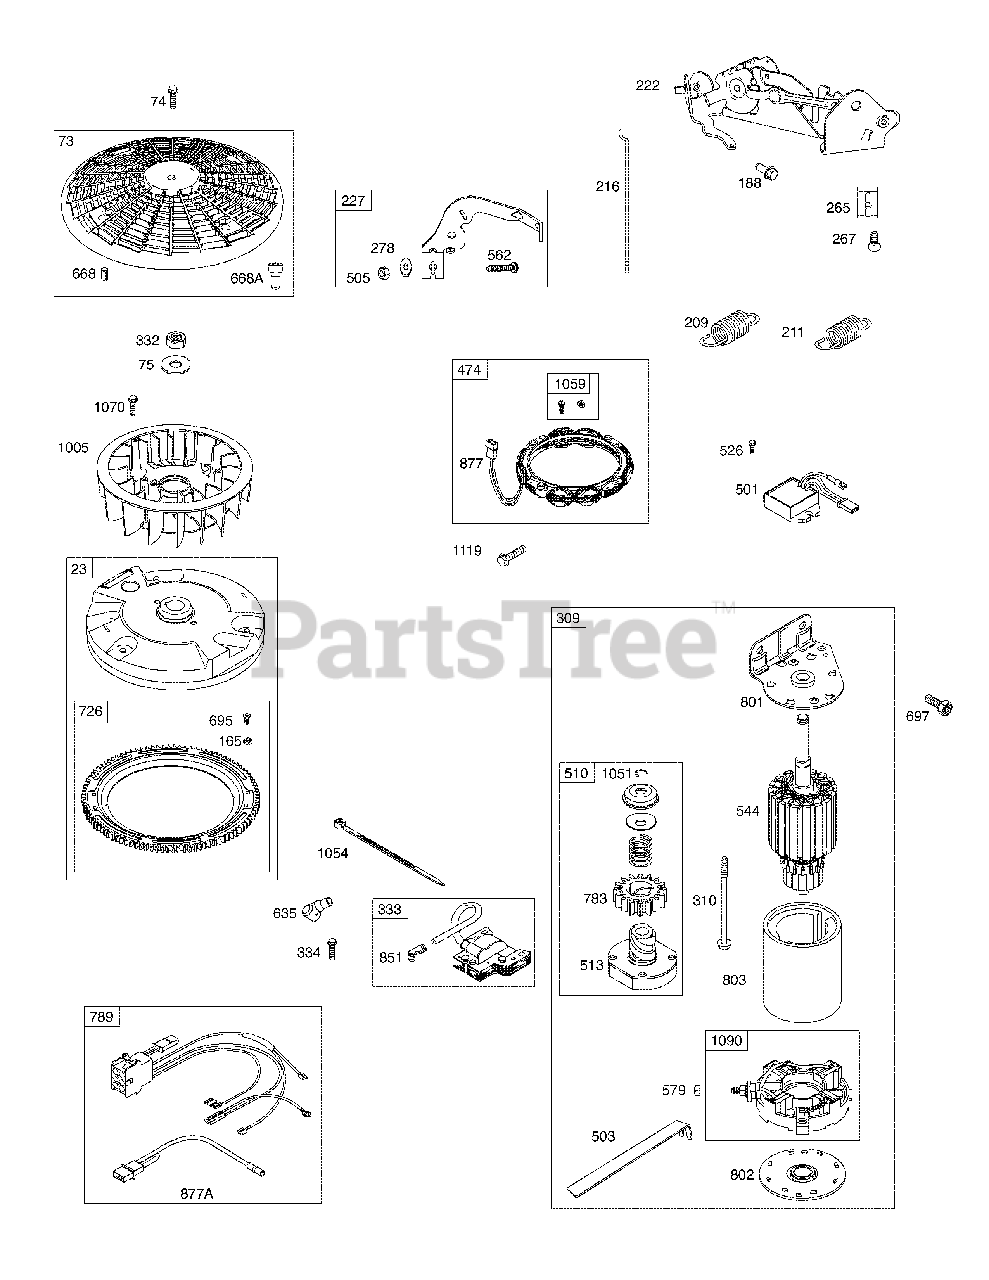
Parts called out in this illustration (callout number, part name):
1	Cylinder Assembly
2	Kit-Bushing/Seal (Magneto Side)
3	Oil Seal (Magneto Side)
4	EngineSump
5	Cylinder Head (Cylinder #1)
5A	Cylinder Head (Cylinder #2)
7	Cylinder Head Gasket
8	Breather Assembly
9	Breather Gasket
10	Screw (Breather Assembly)
11	Breather Tube
12	Crankcase Gasket
13	Screw (Cylinder Head)
15	Oil Drain Plug
16	Crankshaft
20	Oil Seal (PTO Side)
22	Screw (Crankcase Cover/Sump)
23	Flywheel
24	Flywheel Key
25	Piston Assembly (Standard)
25	Piston Assembly (.020" Oversize)
26	Ring Set (Standard)
26	Ring Set (.020" Oversize)
27	Piston Pin Lock
28	Piston Pin
29	Connecting Rod
32	Screw (Connecting Rod)
33	Exhaust Valve
34	Intake Valve
35	Valve Spring (Intake)
36	Valve Spring (Exhaust)
40	Valve Retainer
42	Valve Keeper
45	Valve Tappet
48	Short Block
50	Intake Manifold
51	Intake Gasket
51A	Intake Gasket
53	Stud (Carburetor)
54	Screw (Intake Manifold)
73	Rotating Screen
74	Screw (Rotating Screen)
75	Washer (Flywheel)
95	Screw (Throttle Valve)
98	Idle Speed Kit
104	Float Hinge Pin
105	Float Needle Valve
108	Choke Valve
117	Main Jet (Standard) (Left Jet)
117A	Main Jet (Standard) (Right Jet)
118	Main Jet (High Altitude) (Left Jet)
118A	Main Jet (High Altitude) (Right Jet)
121	Carburetor Overhaul Kit
125	Carburetor
130	Throttle Valve
131	Throttle Shaft Kit
133	Carburetor Float
135	Fuel Transfer Tube
137	Float Bowl Gasket
141	Choke Shaft Kit
142	Carburetor Nozzle
146	Timing Key
150	Nozzle Gasket
163	Air Cleaner Gasket
165	Nut (Ring Gear)
177	O-Ring Seal (Dipstick)
187	Fuel Line (Cut to Required Length)
188	Screw (Control Bracket)
192	Rocker Arm Adjuster
197	Screw (Back Plate)
209	Governor Spring (Yellow/Black)
211	Governed Idle Spring (Orange)
212	Throttle Link
216	Choke Link
217	Choke Return Spring
219	Governor Gear
220	Washer (Governor Gear)
221	Governor Cup
222	Control Bracket
227	Governor Control Lever
231	Screw (Choke Valve)
239	Oil Pressure Switch
240	Fuel Filter
250	Breather Retainer
252	Oil Collector
265	Casing Clamp
267	Screw (Casing Clamp)
276	Sealing Washer (Fuel Solenoid)
278	Washer (Governor Control Lever)
287	Screw (Dipstick Tube)
304	Blower Housing
305	Screw (Blower Housing)
305A	Screw (Blower Housing to Intake Elbow)
306	Cylinder Shield (Cylinder #2)
307	Screw (Cylinder Shield) (1.4-20 x 2.3)
309	Starter Motor
310	Screw (Starter Motor)
332	Nut (Flywheel)
333	Magneto Armature
334	Screw (Magneto Armature)
337	Spark Plug
358	Engine Gasket Set
385	Screw (Fuel Pump)
387	Fuel Pump
404	Washer (Governor Crank)
415	Plug (Oil Pressure Switch)
418	Carburetor Plate
431	Intake Elbow
445	Air Cleaner Cartridge Filter
447	Screw (Air Guide Cover) 10-24 x 7.16)
447A	Screw (Air Guide Cover)
467	Air Cleaner Knob
474	Alternator
501	Regulator
503	Starter Strap
505	Nut (Governor Control Lever)
510	Starter Drive
513	Drive Clutch
523	Dipstick
524	Dipstick Tube Seal
525	Dipstick Tube
526	Screw (Regulator)
544	Starter Armature
552	Governor Crank Bushing
552A	Governor Crank Bushing
562	Screw (Governor Control Lever)
573	Back Plate
579	Nut (Starter Cable)
601	Hose Clamp (Black)
601A	Hose Clamp (Green)
615	Governor Shaft Retainer
616	Governor Crank
617	O-Ring Seal (Intake Manifold) (Red)
628	Screw (Fuel Pump Bracket)
633	Choke Seal/Throttle Shaft
635	Spark Plug Boot
654	Nut (Carburetor)
668	Spacer (Rotating Screen)
668A	Spacer (Rotating Screen)
672	Carburetor Plate Gasket
691	Governor Shaft Seal
695	Screw (Ring Gear)
697	Screw (Drive Cap)
718	Locating Pin
741	Timing Gear
742	E-Ring Retainer (Governor Crank)
750	Screw (Oil Pump Cover)
783	Pinion Gear
788	Fuel Pump Bracket
789	Wiring Harness
798	Screw (Rocker Arm)
803	Starter Housing
847	Dipstick/Tube Assembly
851	Spark Plug Terminal
865	Air Guide Cover (Cylinder #1)
865A	Air Guide Cover (Valley)
868	Valve Seat
877	Alternator Wire/Connector
877A	Alternator Wire/Connector
883	Exhaust Gasket
914	Screw (Rocker Cover)
918	Vacuum Hose
943	O-Ring Seal (Oil Pump Cover)
947	Fuel Solenoid
965	Oil Pump Cover
967	Pre-Cleaner Filter
968	Air Cleaner Cover
975	Float Bowl
987	Throttle Shaft Seal
1005	Flywheel Fan
1013	Oil Filter Nipple
1017	Oil Pump Screen
1022	Rocker Cover Gasket
1023	Rocker Cover (Cylinder #1)
1023A	Rocker Cover (Cylinder #2)
1026	Push Rod (Exhaust)
1026A	Push Rod (Intake)
1027	Oil Filter
1029	Rocker Arm
1036	Emissions Label
1040	Trim Plate
1051	Retaining Ring (Starter Drive)
1058	Operator's Manual
1059	Screw/Washer Kit (Alternator)
1070	Screw (Flywheel Fan)
1090	Brush Retainer
1095	Valve Gasket Set
1100	Rocker Arm Pivot
1119	Screw (Alternator)
1124	O-Ring Seal (Fuel Transfer Tube)
1124A	O-Ring Seal (Fuel Transfer Tube)
1126	Screw (Fuel Transfer Tube)
1127	Screw (Fuel Bowl)
1128	Screw (Carburetor Nozzle)
1169	Screw (Carburetor Plate)
1329	Replacement Engine
